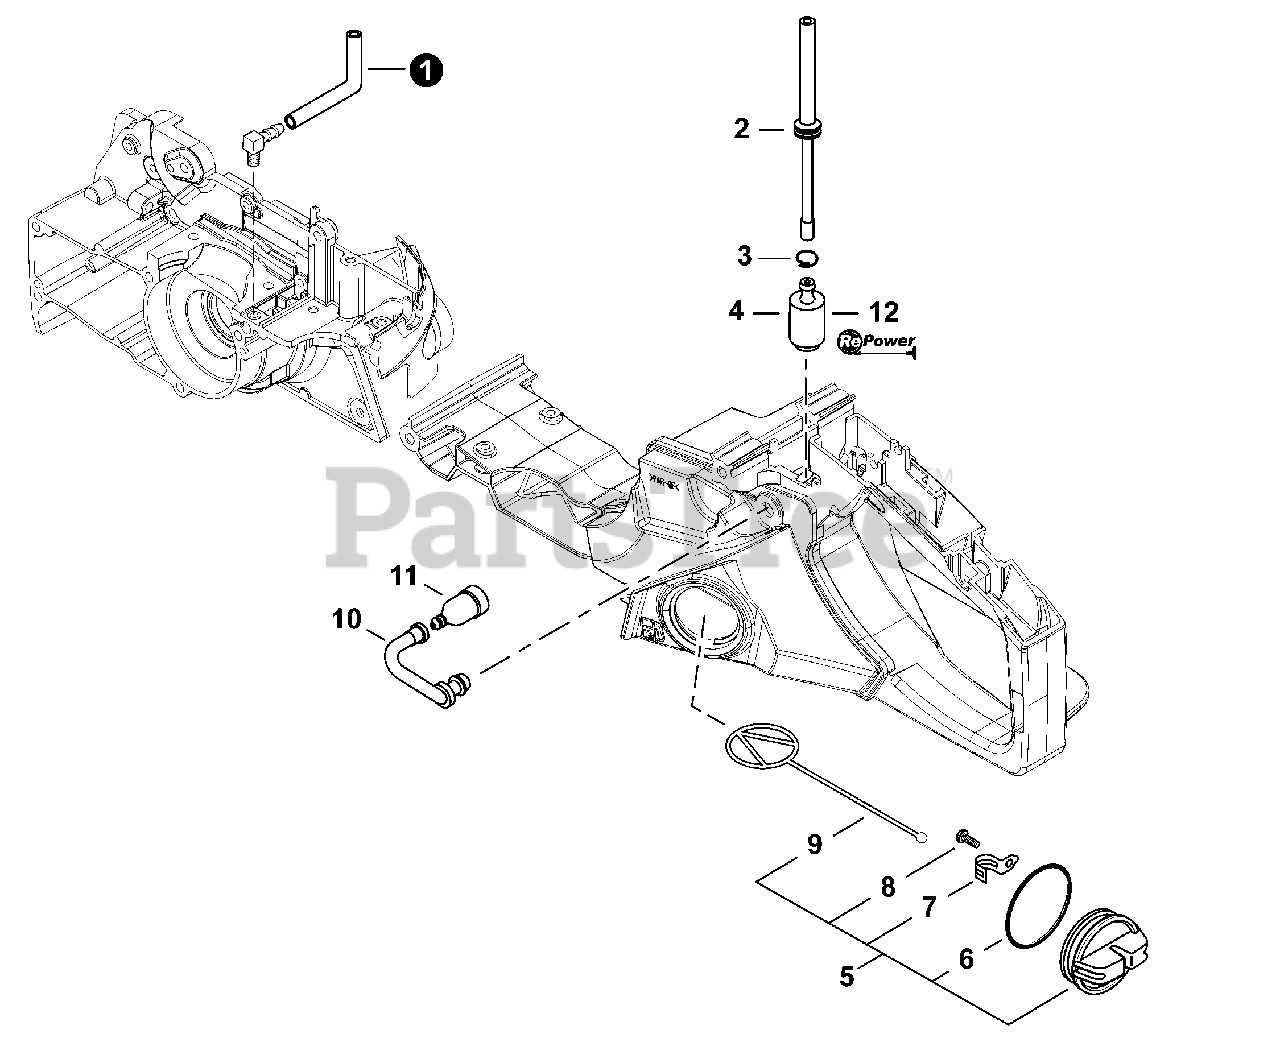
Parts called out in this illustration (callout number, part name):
1	PIPE, PULSE
2	PIPE, FUEL
3	CLIP Ø6
4	FILTER, FUEL
5	CAP ASSY, FUEL
6	O-RING 29
7	RETAINER, CONNECTOR
8	SCREW, TAPPING 3×8
9	CONNECTOR, CAP L= 60 MM
10	PIPE, FUEL VENT
11	VENT ASSY
12	TUNE-UP KIT - REPOWER
